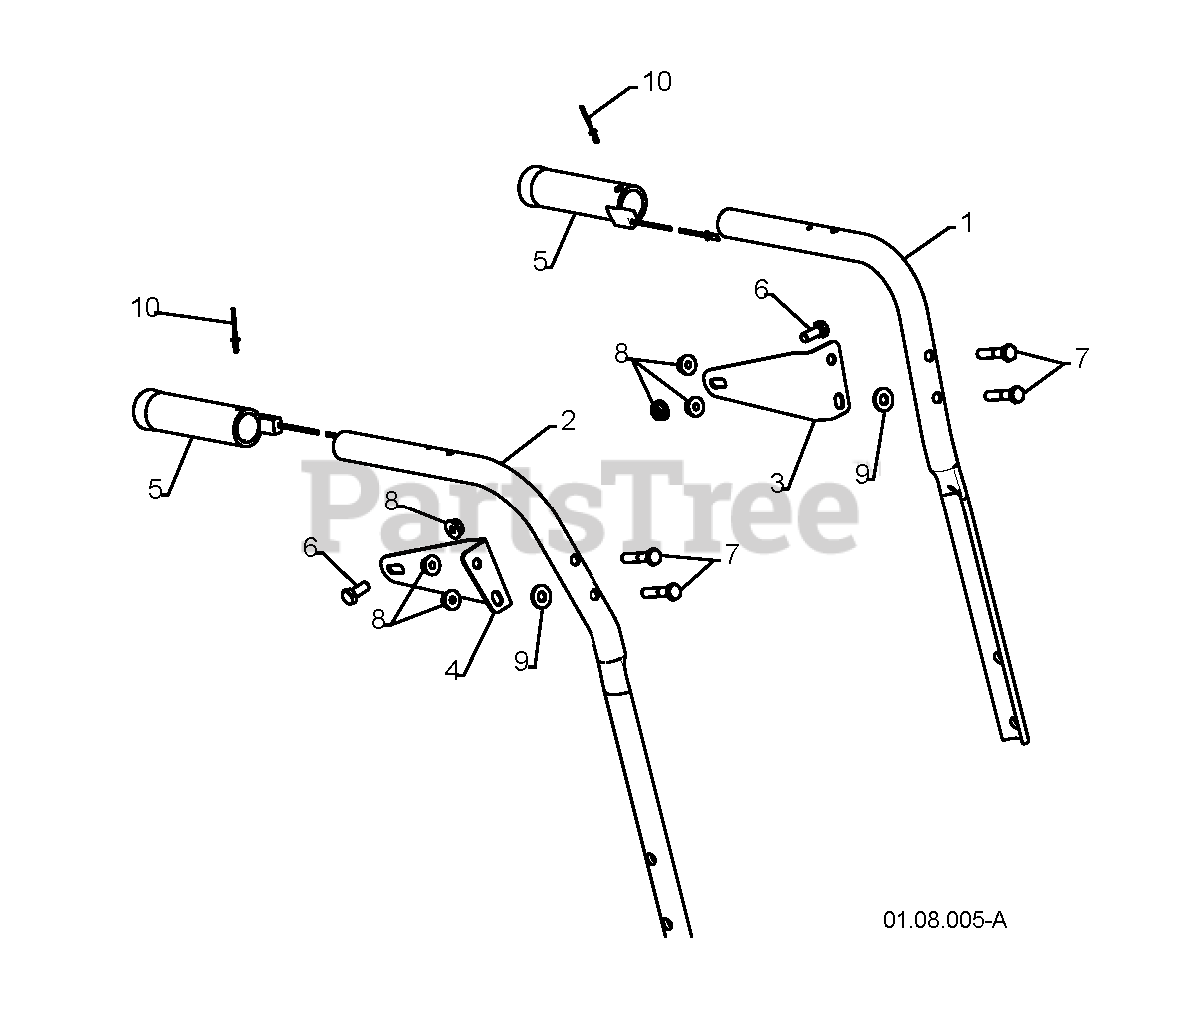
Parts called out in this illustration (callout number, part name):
1	TUBE.HANDLE.PLOW.LH.BLACK
2	TUBE.HANDLE.PLOW.RH.BLACK
3	BRKT.PANEL.LH.INT
4	BRKT.PANEL.RH.INT
5	GRIP.HANDLE.HEATED
6	BOLT.FIN.HEX.5/16-18X3/4
7	HEX BOLT
8	NUT.LOCK.5/16-18
9	WASHER.20X8.5
10	RIVET.POP.1/8X
